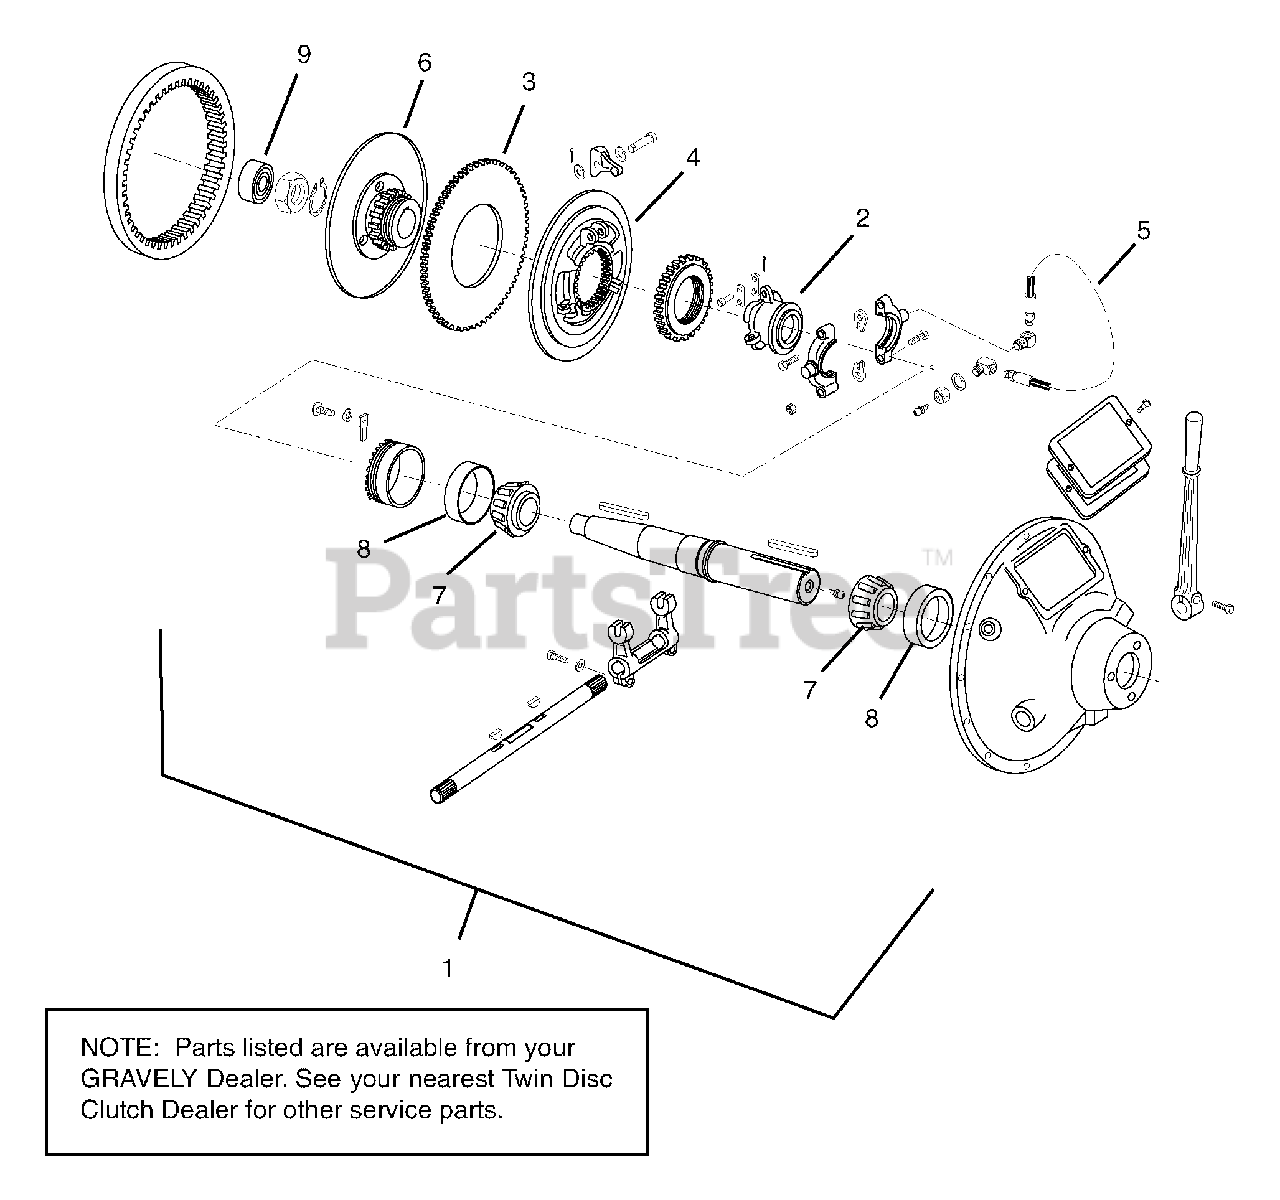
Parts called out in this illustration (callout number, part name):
1	Clutch Assembly
2	Sleeve-Sliding
3	Plate-Friction
4	Plate-Pressure
5	Hose-Grease
6	Plate-Hub & Backing
7	Bearing-Cone
8	Bearing-Cup
9	Bearing-Ball-Pilot
